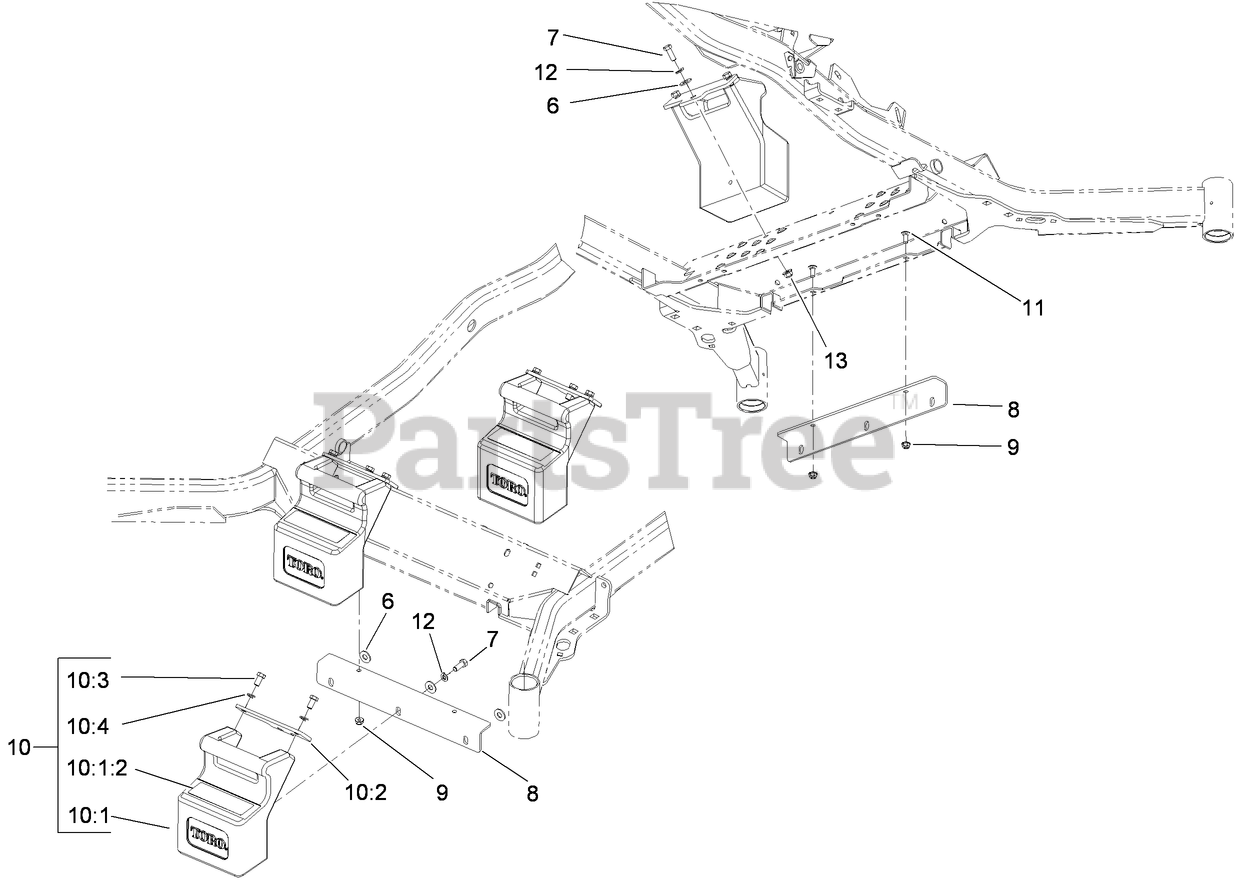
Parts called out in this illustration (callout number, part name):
6	WASHER-FLAT
7	SCREW-HH
8	BRACKET-MOUNT, WEIGHT
9	NUT-HF, NI
10	WEIGHT ASM
10:1	OBS WEIGHT
10:1:2	Decal-Warning, Counterweight
10:2	TAB-SUPPORT, WEIGHT
10:3	SCREW-HH
10:4	WASHER-LOCK
11	SCREW-CARR
12	WASHER-LOCK
13	NUT-HF, NI
